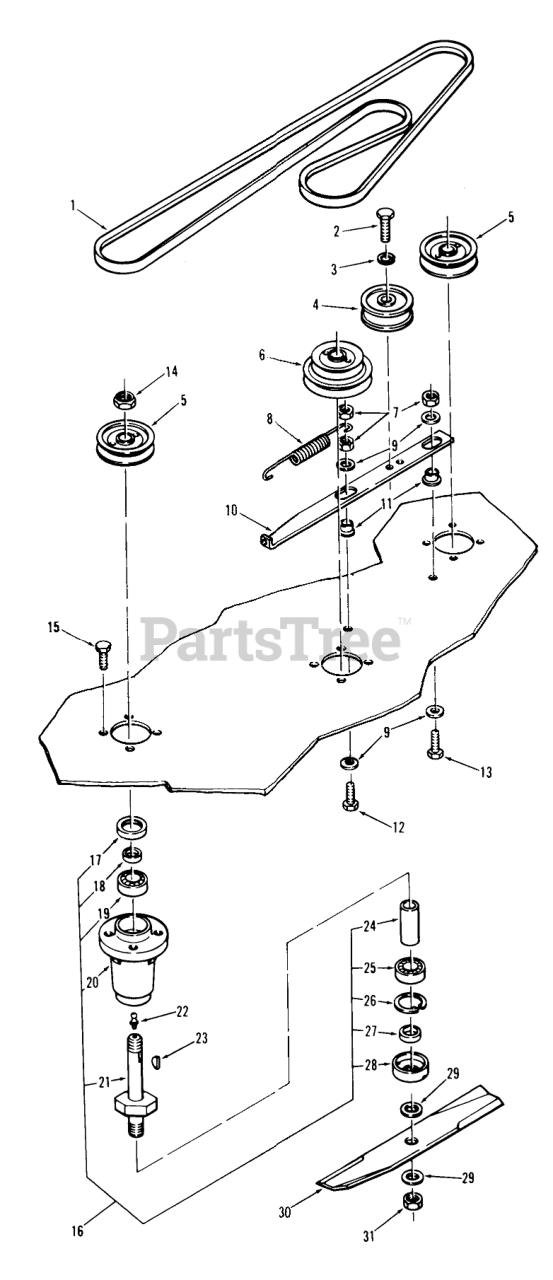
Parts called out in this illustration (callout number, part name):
1	V-BELT
2	BOLT HEX SPECIAL
3	LOCKWASHER
4	Idler Pulley
5	PULLEY-BLADE DRIVE
6	PULLEY-48 MOWER SPDL
7	Nut
8	SPRING-EXTENSION
9	WASHER
10	BAR-IDLER SUPPORT
11	Bushing/Spacer
12	Bolt
13	Bolt
14	Nut
15	Bolt
16	Spindle Assembly
18	SPACER-SEAL
19	BEARING-BALL
20	HOUSING-SPINDLE
21	Spindle Shaft
22	Zerk
23	Hi-Pro Key 3/16 x 5/8
24	SPACER
25	BEARING-BALL
26	Ring-Snap
27	SPACER-BLADE
28	CUP-SPINDLE
29	Washer
30	Blade
31	Nut
